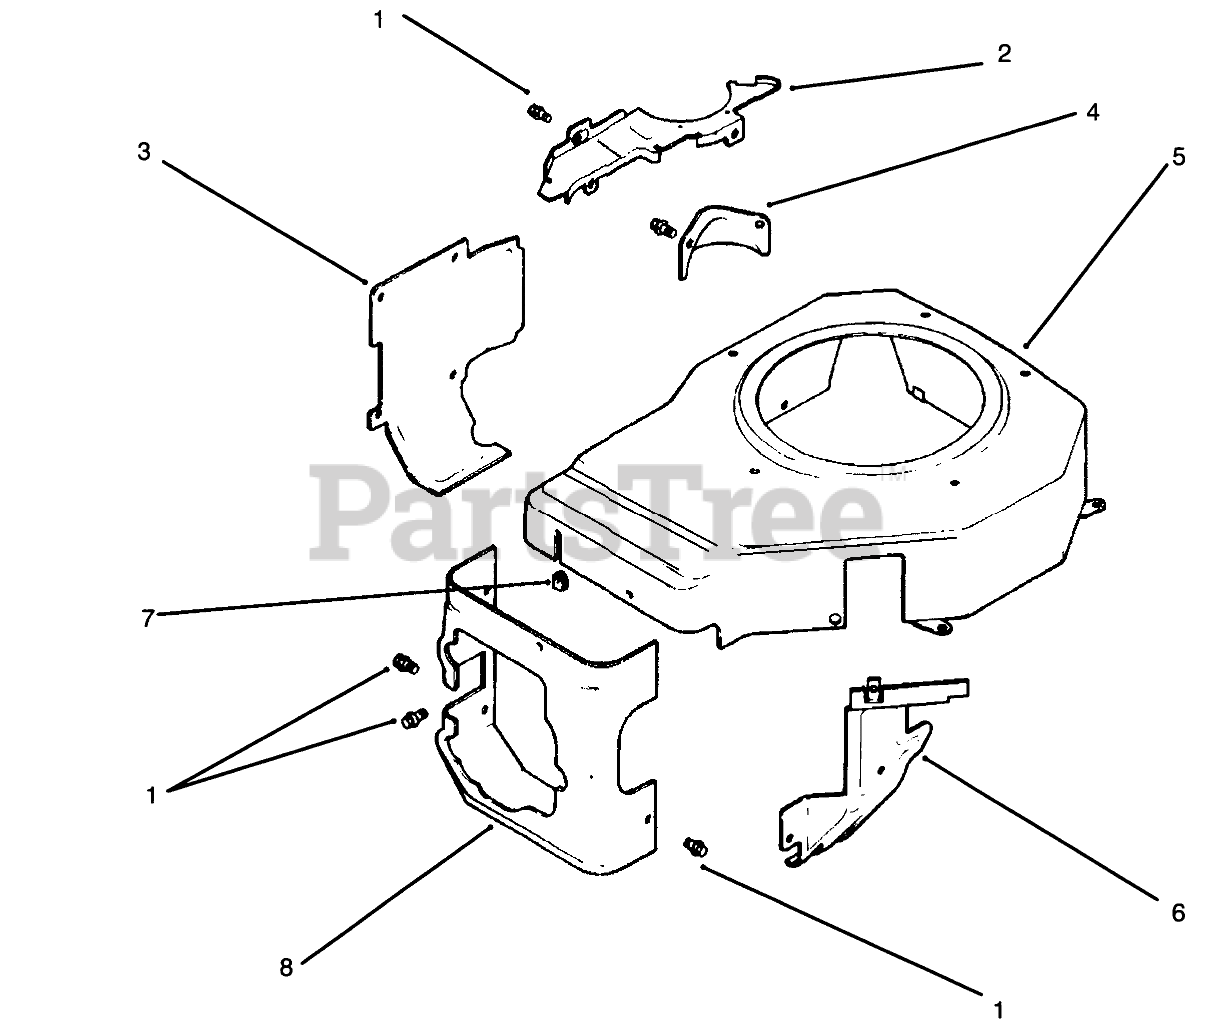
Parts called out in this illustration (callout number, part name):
2	Plate Blower
3	Babe-Cylinder Barrel
4	Cover-Starter
5	Cover-Housing
6	Bade-Carburetor
7	Grommet
8	Baffle-Cylinder Head
